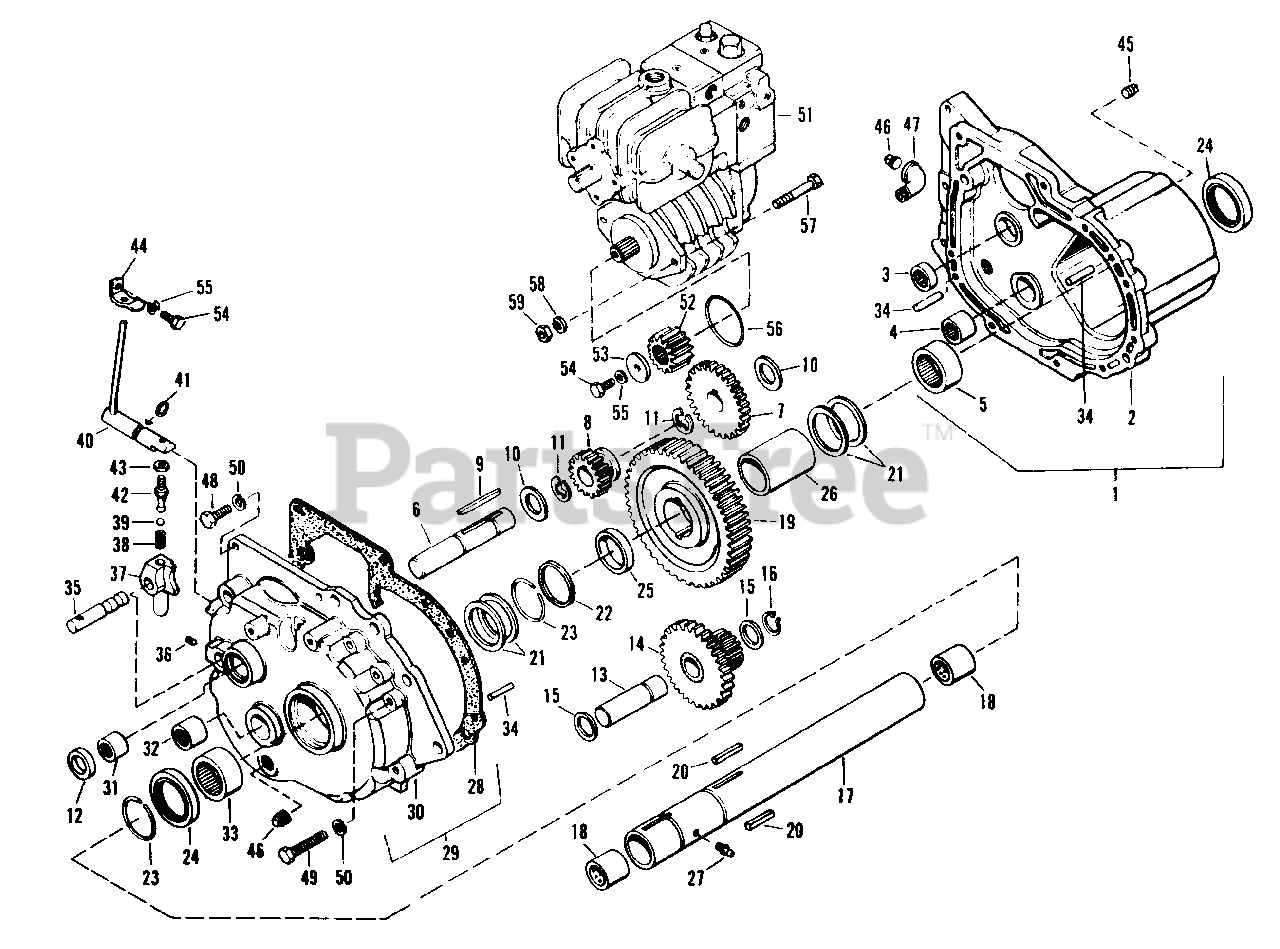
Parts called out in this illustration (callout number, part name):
1	Gear Case Complete (includes 2 thru 5)
2	Gear Case
3	Needle Bearing
4	Needle Bearing
5	Needle Bearing
6	Brake Shaft
7	Gear - 1st Interm.
8	Sliding Pinion
11	Retainer Ring
13	Shaft, Interm.
14	Pinion & Gear Assembly
16	Retaining Ring
17	Axle Tube Assembly
19	Drive Gear
25	Spacer (R.H. Side)
26	Spacer (L.H. Side)
27	Grease Fitting
28	Gear Case Gasket
29	Gear Case Cover Sub. Assy. (Includes 30, 31, 32, 33)
30	Gear Case Cover
31	Needle Bearing
32	Needle Bearing
33	Needle Bearing
34	Roll Pin, 3/8" x 1"
35	Shifter Shaft
36	Cone Pt. Setscrew, Hollow Hd., 5/16"-18 x 1/2"
37	Shift Fork
39	Shift Lock Ball
40	Shift Shaft Assembly
43	Hex Jam Nut, 5/16"-24
44	Lift Lever Latch
45	Pipe Plug, 1/4"
46	Pipe Plug, 3/8"
47	Street Elbow, 3/8"
48	Hex Cap Screw, 5/16"-18 x 1"
49	Hex Cap Screw, 5/16"-18 x 2"
50	Lock Washer, 5/16"
51	Hydrostatic Pump & Motor Unit
52	Motor Shaft Pinion
54	Hex Cap Screw, 5/16"-24 x 5/8"
55	Lock Washer, 5/16"
57	Hex Cap Screw, 7/16"-14 x 4"
58	Lock Washer, 7/16"
59	Hex Nut, Full, 7/16"-14
